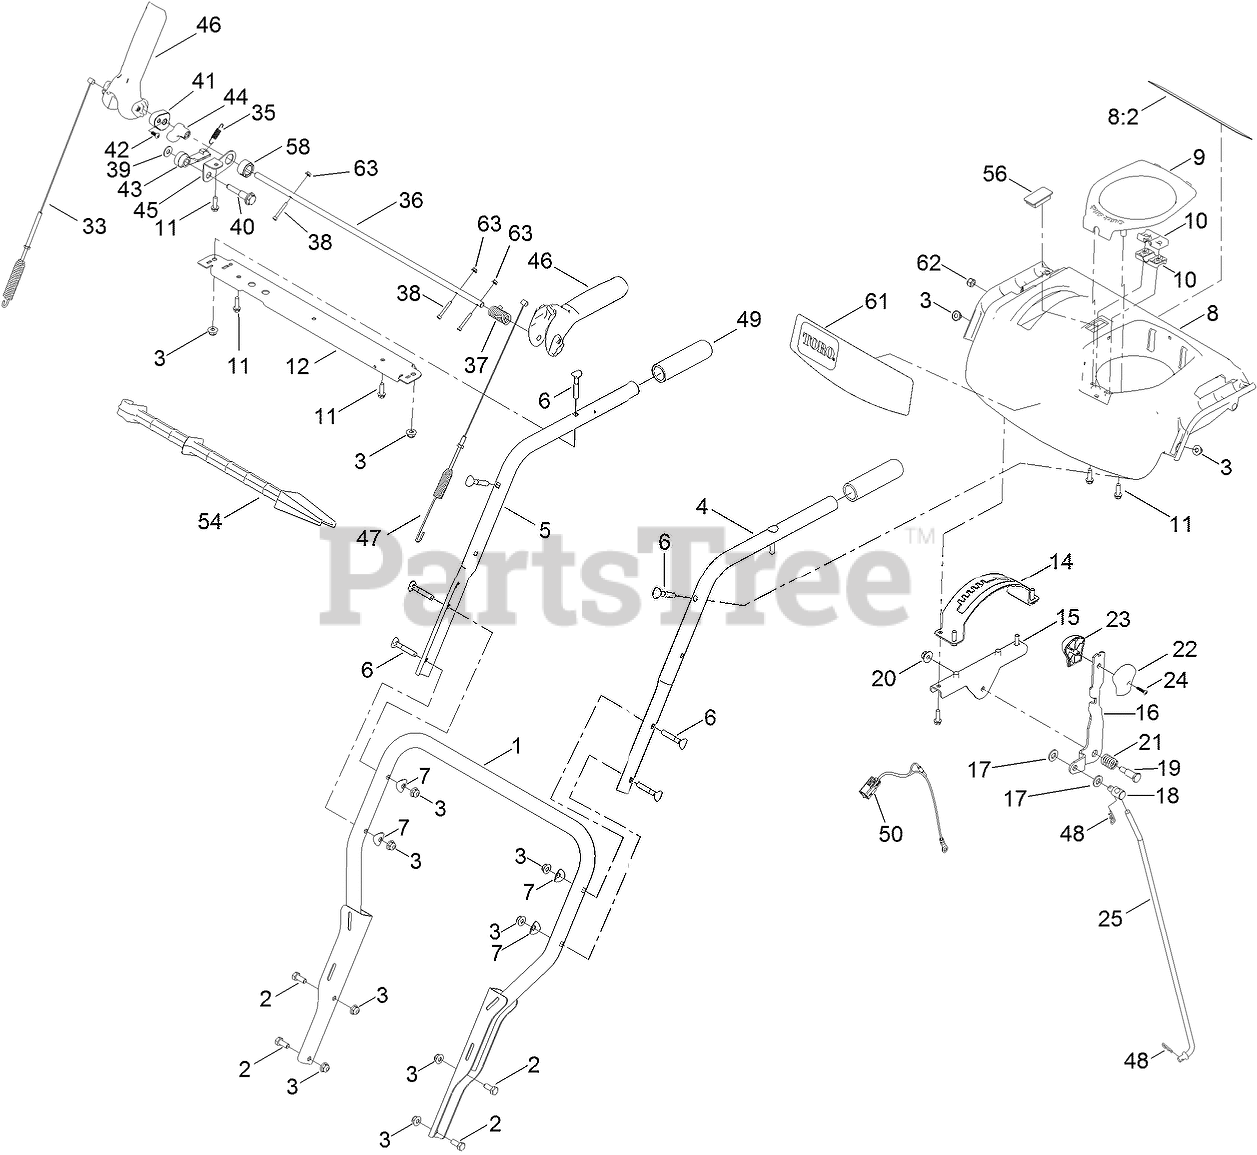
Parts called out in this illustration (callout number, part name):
1	LOWER HANDLE ASM
2	SCREW-HH
3	NUT-HF
4	HANDLE-UPPER, LH
5	HANDLE-UPPER, RH
6	SCREW-HANDLE
7	WASHER-CUP
8	PANEL-CONTROL, W/GRAPHICS
8:2	DECAL-SAFETY
9	COVER-QUICKSTICK
10	SUPPORT-ROD
11	SCREW-PLASTITE, HWH
12	BRACE-CONSOLE
14	GATE-SHIFT
15	BRACKET-SHIFT
16	SELECTOR-SPEED
17	WASHER-FLAT
18	TRUNNION-ROD
19	SCREW-SHOULDER, HH
20	NUT-HF
21	SPRING-COMPRESSION
22	SHIFT KNOB ASM
22	KNOB-SHIFT, LH
23	KNOB-SHIFT, RH
24	SCREW-PPH
25	ROD-SHIFT
33	CABLE-AUGER
35	SPRING-LOCKOUT, HANDLE
36	ROD-LOCKOUT
37	SPRING-TORSION, HANDLE RETURN
38	SCREW-HSH
39	WASHER-FLAT
40	SCREW-SHOULDER
41	LOCK-HANDLE
42	SCREW-PPH
43	LATCH-LOCKOUT
44	CAM-LOCKOUT
45	LINK-LOCKOUT
46	LEVER-CONTROL
47	CABLE-TRACTION
48	PIN-HAIR
49	GRIP-HANDLE
50	HARNESS-WIRE, LED
54	STICK-CLEANOUT
56	PLUG-HOLE
58	COLLAR-CAM
61	DECAL-CONSOLE
62	NUT-HEX
63	NUT-LOCK ROHS
